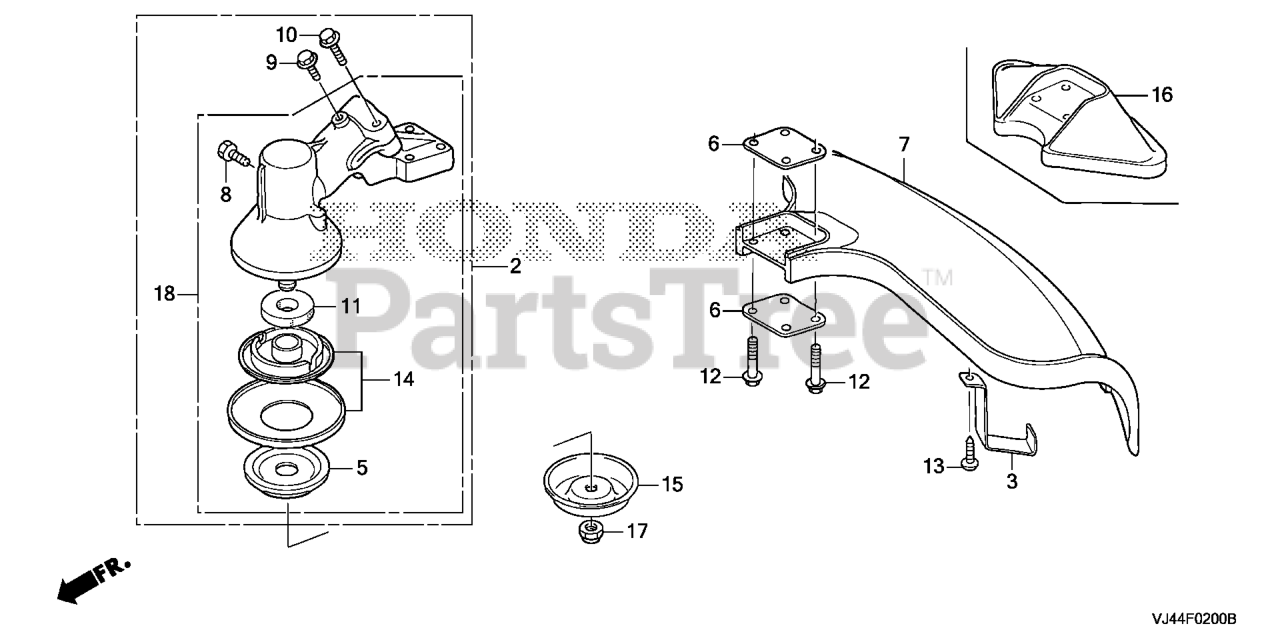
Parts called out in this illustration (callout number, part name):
2	CASE ASSY., GEAR
3	PLATE, NYLON CUTTING
5	HOLDER B, BLADE
6	SPACER, DEFLECTOR
7	DEFLECTOR, GRASS
8	BOLT, HEX. (8X10)
9	BOLT-WASHER (5X12)
10	BOLT-WASHER (5X25)
12	BOLT-WASHER (5X28)
13	SCREW, TAPPING (5X12) (PO)
14	HOLDER, BLADE
